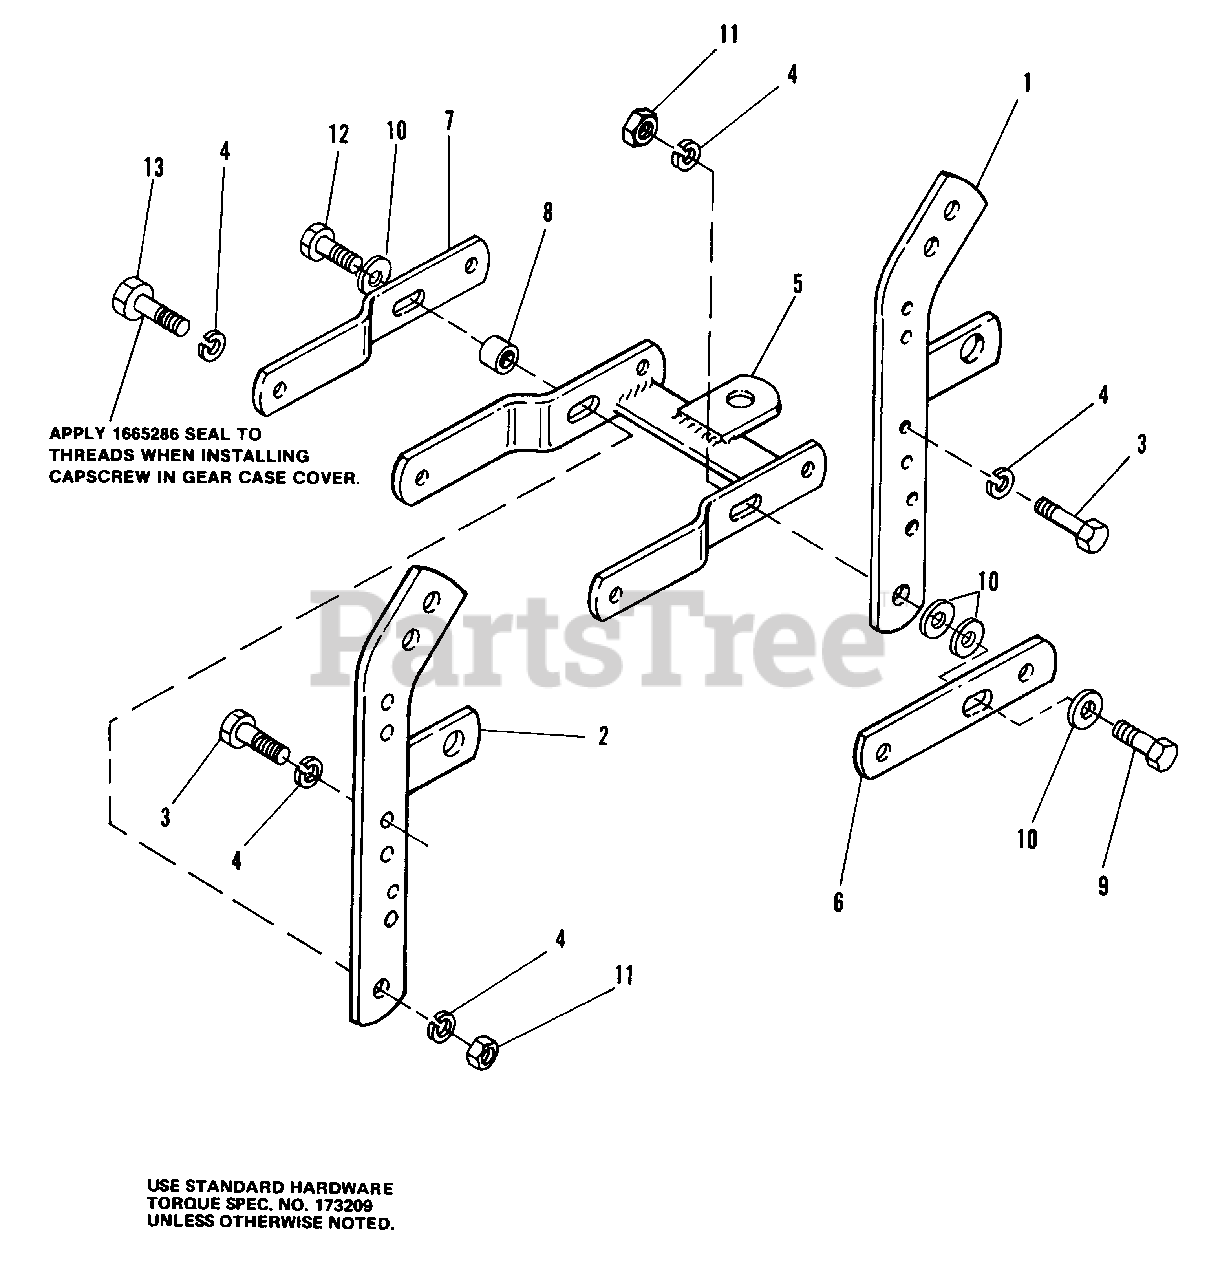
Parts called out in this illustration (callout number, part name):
1	L.H. ARM ASSEMBLY
2	R.H. ARM ASSEMBLY
3	CAPSCREW, Hex Hd., 7/16-14 x 1
4	LOCKWASHER, 7/16
5	DRAWBAR ASSEMBLY
6	BAR, Pull, L.H.
7	BAR, Draw, R.H.
9	CAPSCREW, Hex Hd., 7/16-14 x 1-1/2
10	WASHER, 7/16
11	NUT, Hex, 7/16-14
12	CAPSCREW, Hex Hd., 7/16-14 x 1-3/4
13	CAPSCREW, Hex Hd., 7/16-14 x 2-1/4
